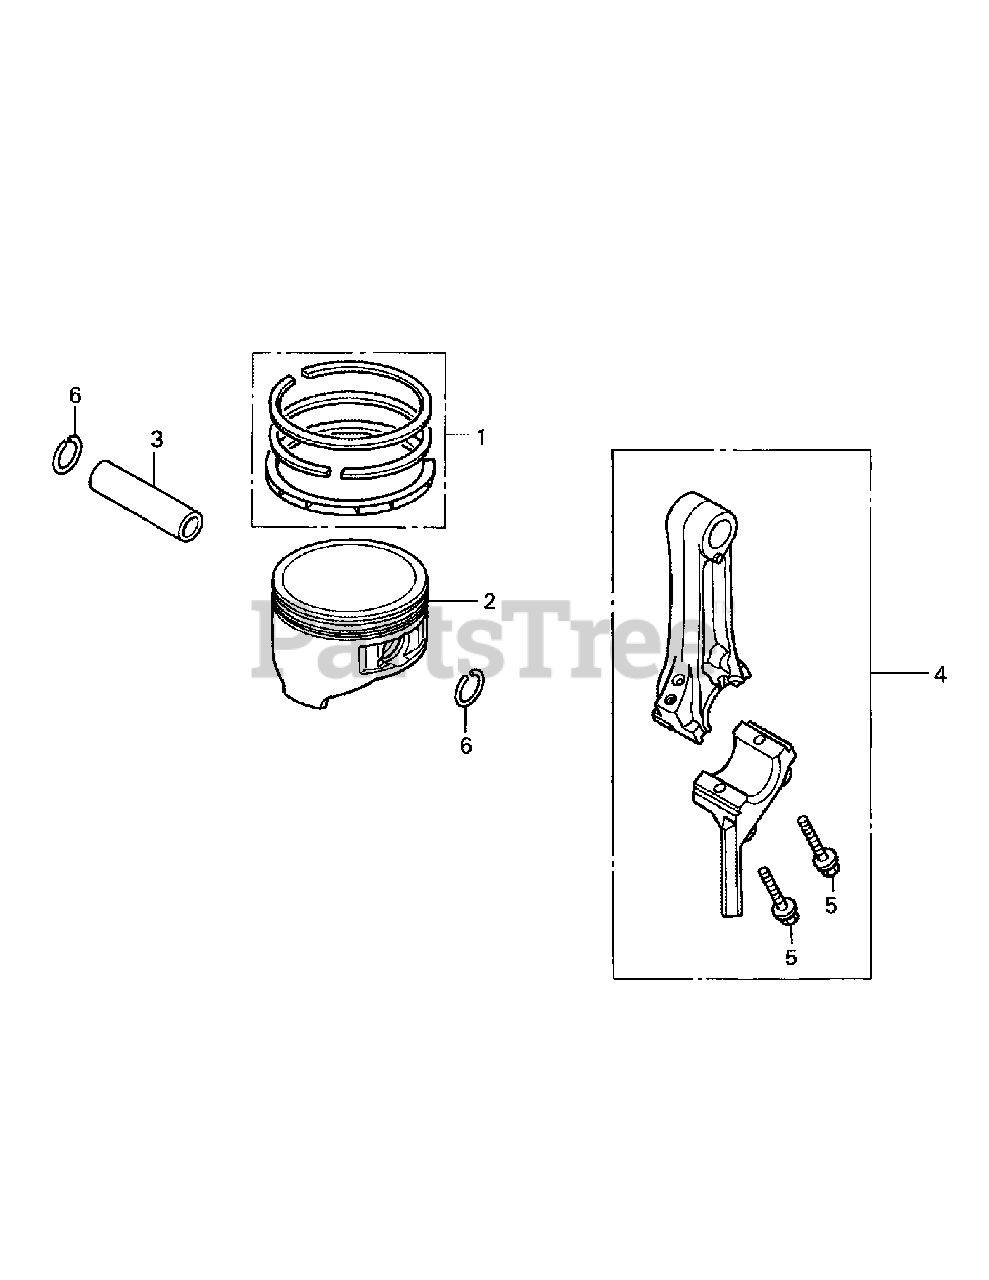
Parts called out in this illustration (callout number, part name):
1	Piston Ring Set (Teikoku)
2	Piston
3	Piston Pin
4	Connecting Rod Assembly
5	Connecting Rod Bolt
6	Piston Pin Clip, 13mm
